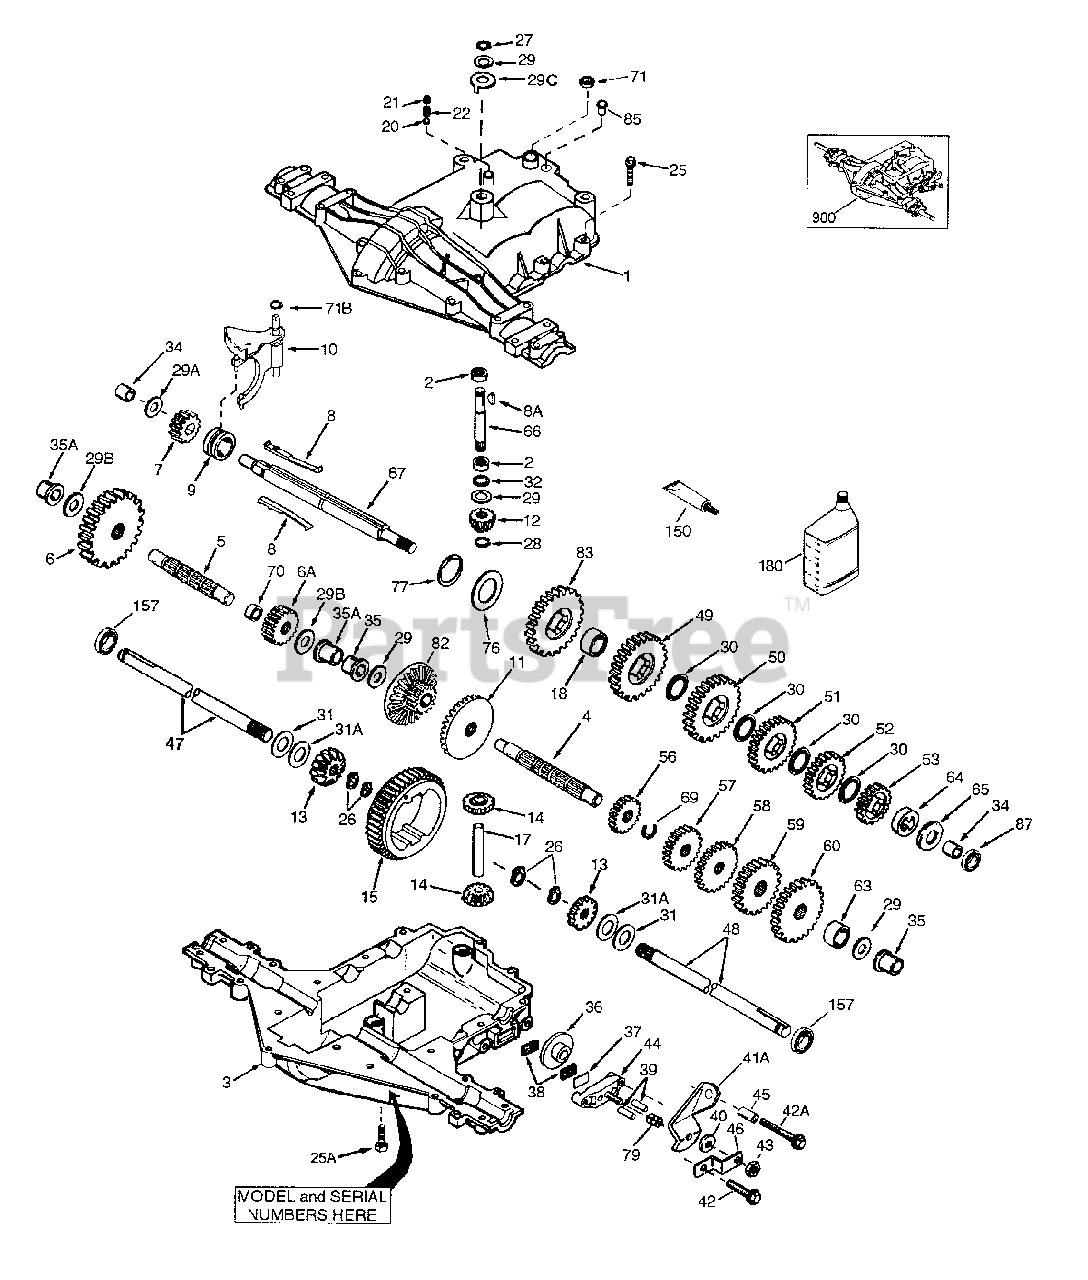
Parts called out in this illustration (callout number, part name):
1	Transaxle Cover
2	Needle Bearing 5/8" ID
3	Transaxle Case
4	Countershaft
5	Output Shaft
6	Spur Gear (38 teeth)
6A	Spur Gear (15 teeth)
7	Spur Gear (11 teeth)
8	Shift Key
8A	Woodruff Key #9
9	Shift Collar
10	Shift Rod & Fork
11	Bevel Gear (30 teeth)
12	Input Bevel Pinion (13 teeth)
13	Bevel Gear (13 teeth)
14	Bevel Pinion (13 teeth)
15	Ring Gear (43 teeth)
17	Drive Pin
20	Ball 5/16" dia
21	Set Screw 3/8-16 x 3/8"
25	Screw 1/4-20 x 1-1/4"
25A	Screw 1/4-20 x 1-3/8"
26	Retaining Ring (pkg of 2)
27	Retaining Ring
28	Retaining Ring
29B	Thrust Washer (.762 ID)
29C	Anti-Rotation Washer .632
31	Washer (.056 wide)
31A	Flat Washer (.062 wide)
32	Oil Seal 5/8"
34	Bushing 9/16"
35	Flanged Bushing 5/8" ID
35A	Flanged Bushing 3/4"
36	Brake Disk
37	Brake Pad Plate
38	Brake Pad (pkg of 2)
39	Dowel Pin
40	Flat Washer
41A	Brake Lever
42	Screw 1/4-20 x 1-1/4"
42A	Screw 1/4-20 x 2-1/4"
43	Locknut 5/16-24
44	Brake Pad Holder
46	Brake Lever Bracket
47	Axle (11-15/16" long)
48	Axle (16-1/2" long)
49	Spur Gear (29 teeth)
50	Spur Gear (23 teeth)
51	Spur Gear (19 teeth)
52	Spur Gear (16 teeth)
53	Spur Gear (15 teeth)
56	Spur Gear (11 teeth)
57	Spur Gear (17 teeth)
58	Spur Gear (21 teeth)
59	Spur Gear (24 teeth)
60	Spur Gear (25 teeth)
63	Countershaft Spacer 1-1/8" x 3/8"
64	Brake Shaft Spacer 1-3/8" x 3/8"
66	Input Shaft
67	Shifter & Brake Shaft
69	Retaining Ring
70	Spacer .890
71	Square Cut Ring
71B	"O" Ring
77	Inverted Retaining Ring
82	Bevel & Spur Gear (30 & 13 teeth)
83	Spur Gear (27 teeth)
85	Oil Fill Plug
87	Oil Seal 9/16"
150	Liquid Gasket RTV Silicone
157	Oil Seal 3/4"
180	Gear Oil 80W90
900	Replacement 205-507B Transaxle
